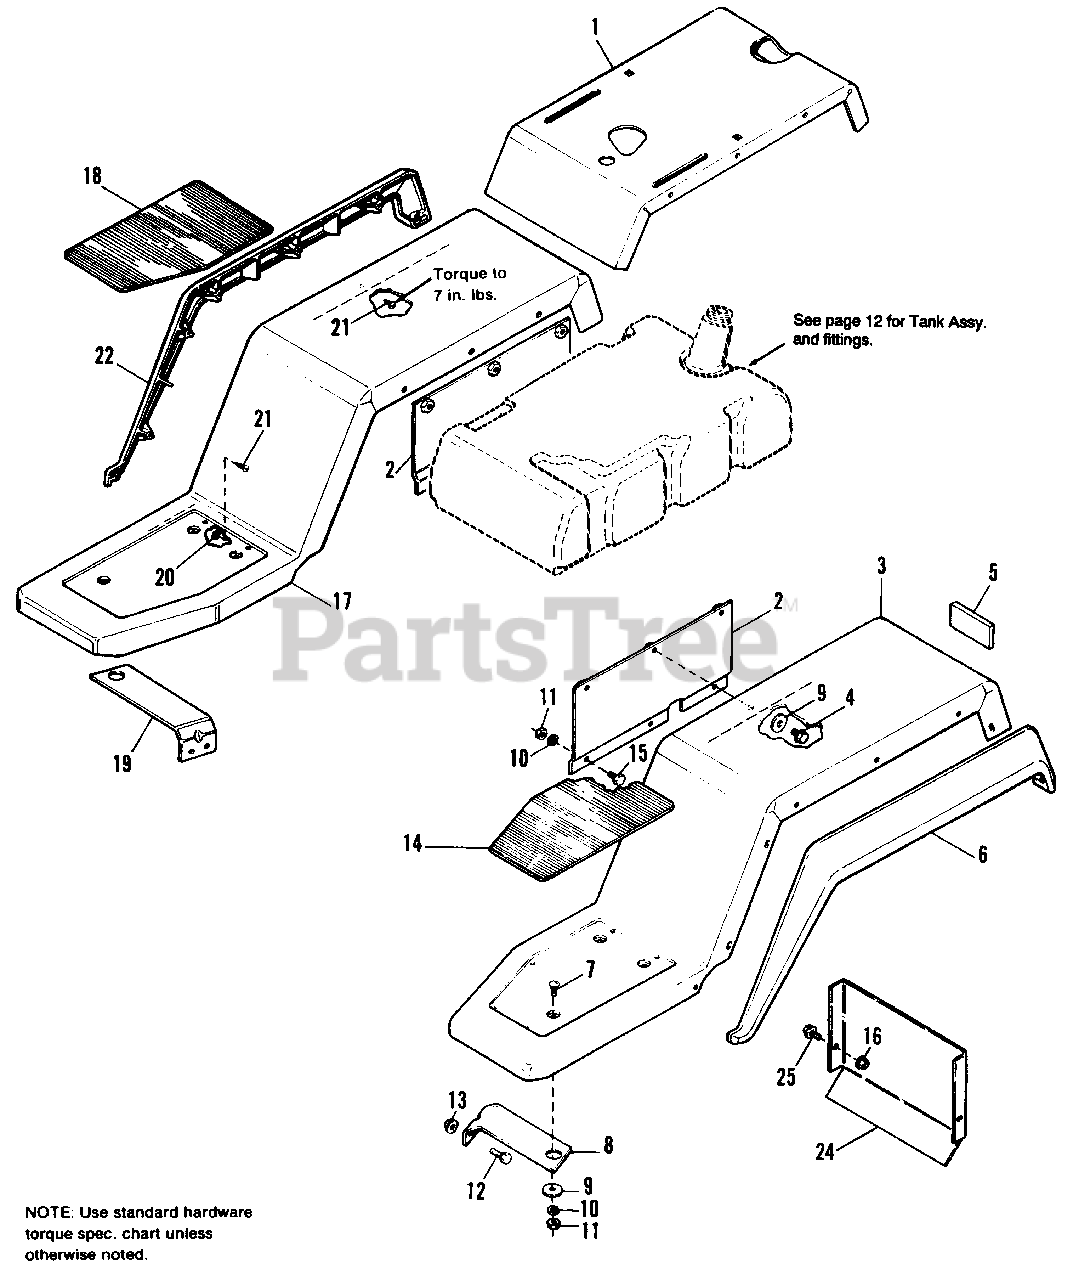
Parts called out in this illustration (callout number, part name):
1	COVER, Fuel Tank
2	FENDER SUPPORT ASSY.
3	FENDER, L.H.
4	SCREW, Taptite, 5/16-18 x 3/4
5	REFLECTOR, Rear
6	FENDER SKIRT, L.H. (except models with 26" tires)
6	FENDER SKIRT L.H. (models with 26" tires only)
7	BOLT Carriage, 5/16-18 x 3/4
8	FOOTREST SUPPORT, Front, L.H.
9	WASHER, Flat, 11/32 x 1-1/2 x 7/64
10	LOCKWASHER, 5/16
11	NUT, 5/16-18
12	CAPSCREW, Hex Hd., 3/8-16 x 7/8
13	LOCKNUT, Whiz, 3/8-16
14	PAD, Footrest, L.H.
15	CAPSCREW, Hex Hd., 5/16-18 x 3/4
16	NUT, Flange Whizlock, 5/16-18
17	FENDER, R.H.
18	PAD, Footrest, R.H.
19	FOOTREST SUPPORT, Front, R.H.
20	LOCKWASHER, 1/4
21	SCREW, Plastite, 1/4-10 x 5/8
22	FENDER SKIRT, R.H. (except models with 26" tires)
22	FENDER SKIRT, R.H. (models with 26" tires only)
24	COVER, Rear Frame
25	SCREW, Flange Whizlock, 5/16-18 x 1
